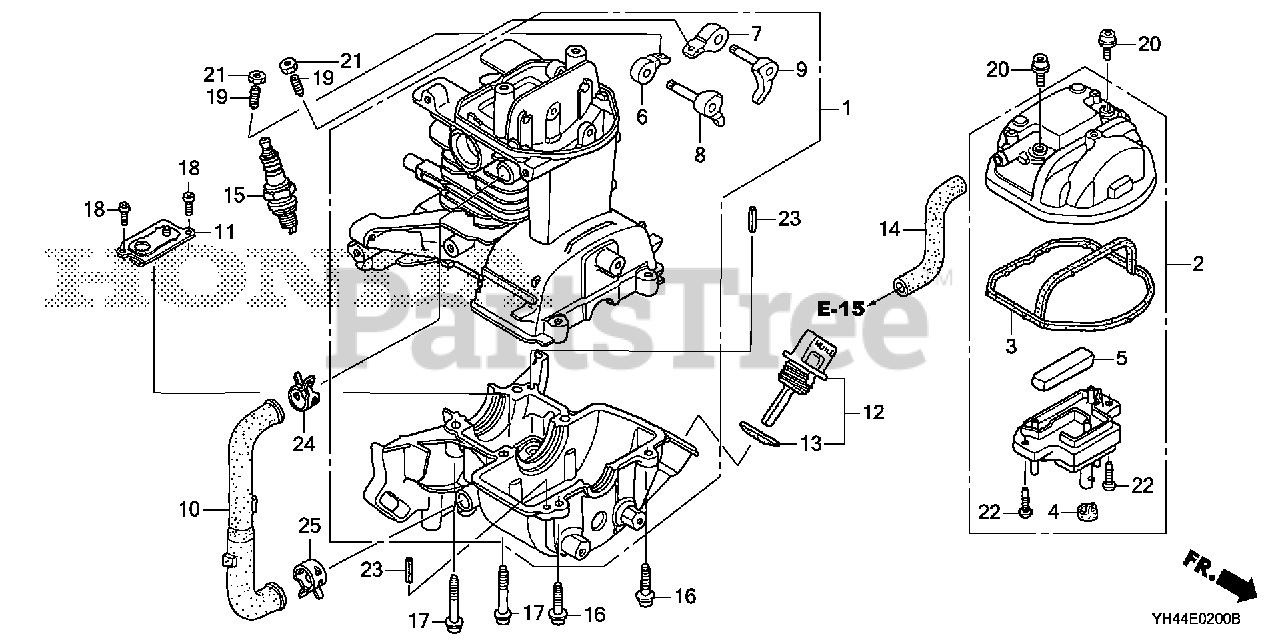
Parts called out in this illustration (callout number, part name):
1	CRANKCASE SET
2	COVER, CYLINDER HEAD
3	SEAL, HEAD COVER
4	GROMMET, HEAD COVER
5	FILTER, BREATHER
6	ARM, IN. VALVE ROCKER
7	ARM, EX. VALVE ROCKER
8	LIFTER, IN. VALVE
9	LIFTER, EX. VALVE
11	PLATE ASSY., OIL OUTLET VALVE
12	CAP ASSY., OIL FILLER
13	GASKET, OIL FILLER CAP
14	TUBE, BREATHER
15	SPARK PLUG (CMR4H) (NGK)
15	SPARK PLUG (CMR5H) (NGK)
15	SPARK PLUG (CMR6H) (NGK)
16	BOLT, SOCKET (5X20)
17	BOLT, SOCKET (5X30)
17	BOLT, SOCKET (5X32)
18	SCREW, PAN (4X8)
19	SCREW, TAPPET ADJUSTING
20	BOLT, SOCKET (5X12)
21	NUT, TAPPET ADJUSTING
22	SCREW, TAPPING (4X12)
23	PIN, SPRING (4X10)
24	CLAMP, TUBE (D12)
25	CLAMP, TUBE (D13)
